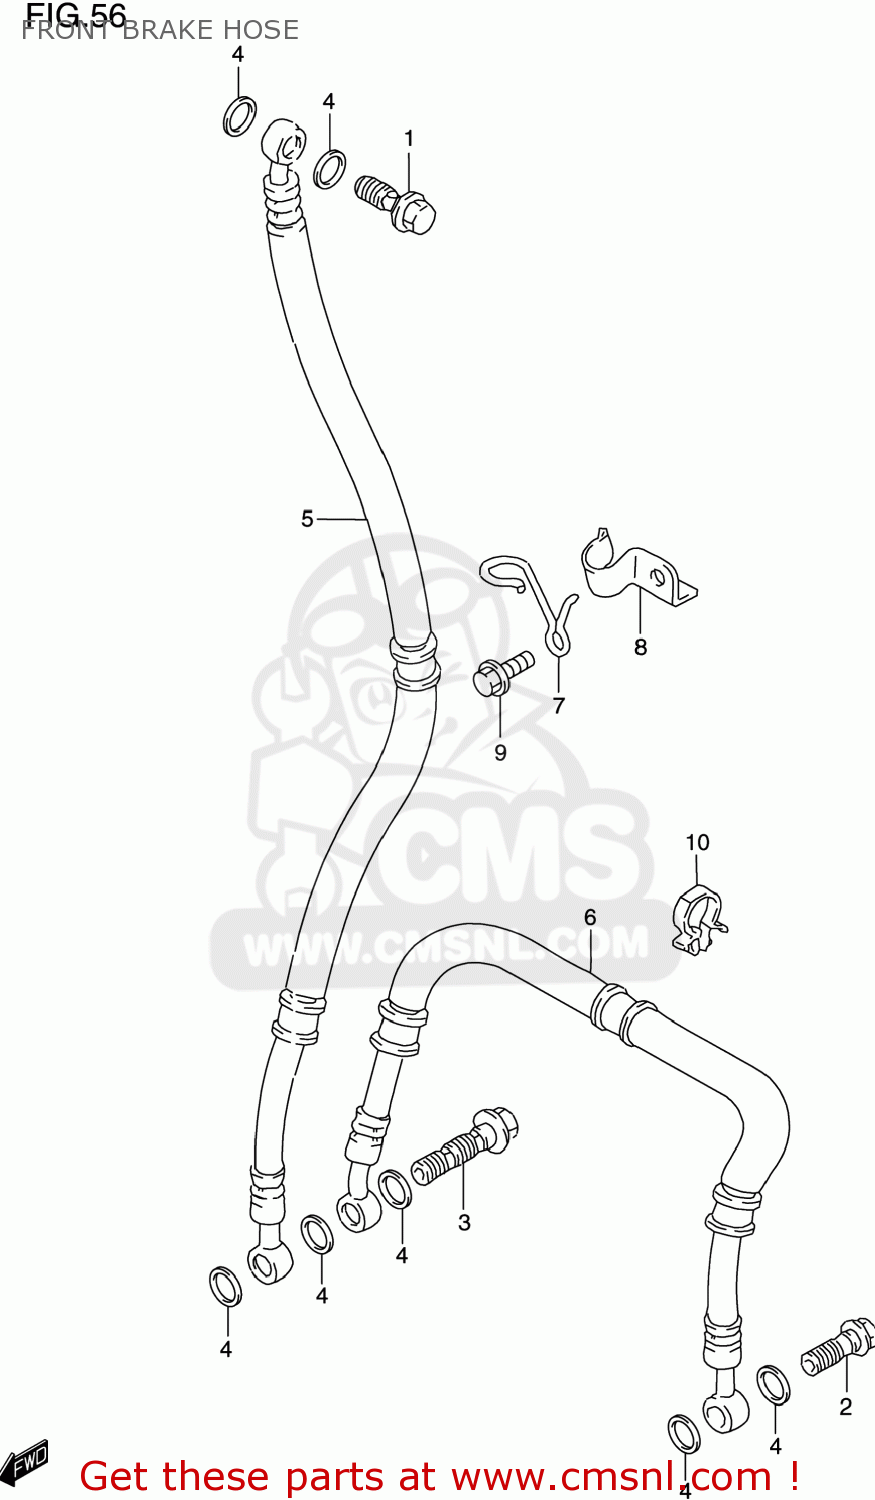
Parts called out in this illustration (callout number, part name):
1	BOLT UNION
2	BOLT UNION
3	BOLT UNION
4	WASHER(10X15X1.5)
5	HOSE,FR BRAKE NO.1
6	HOSE,FR BRAKE NO.2
7	GUIDE,FR BRAKE HOSE NO.1
8	CLAMP,FR BRAKE HOSE UPR
9	BOLT
10	CLAMP
